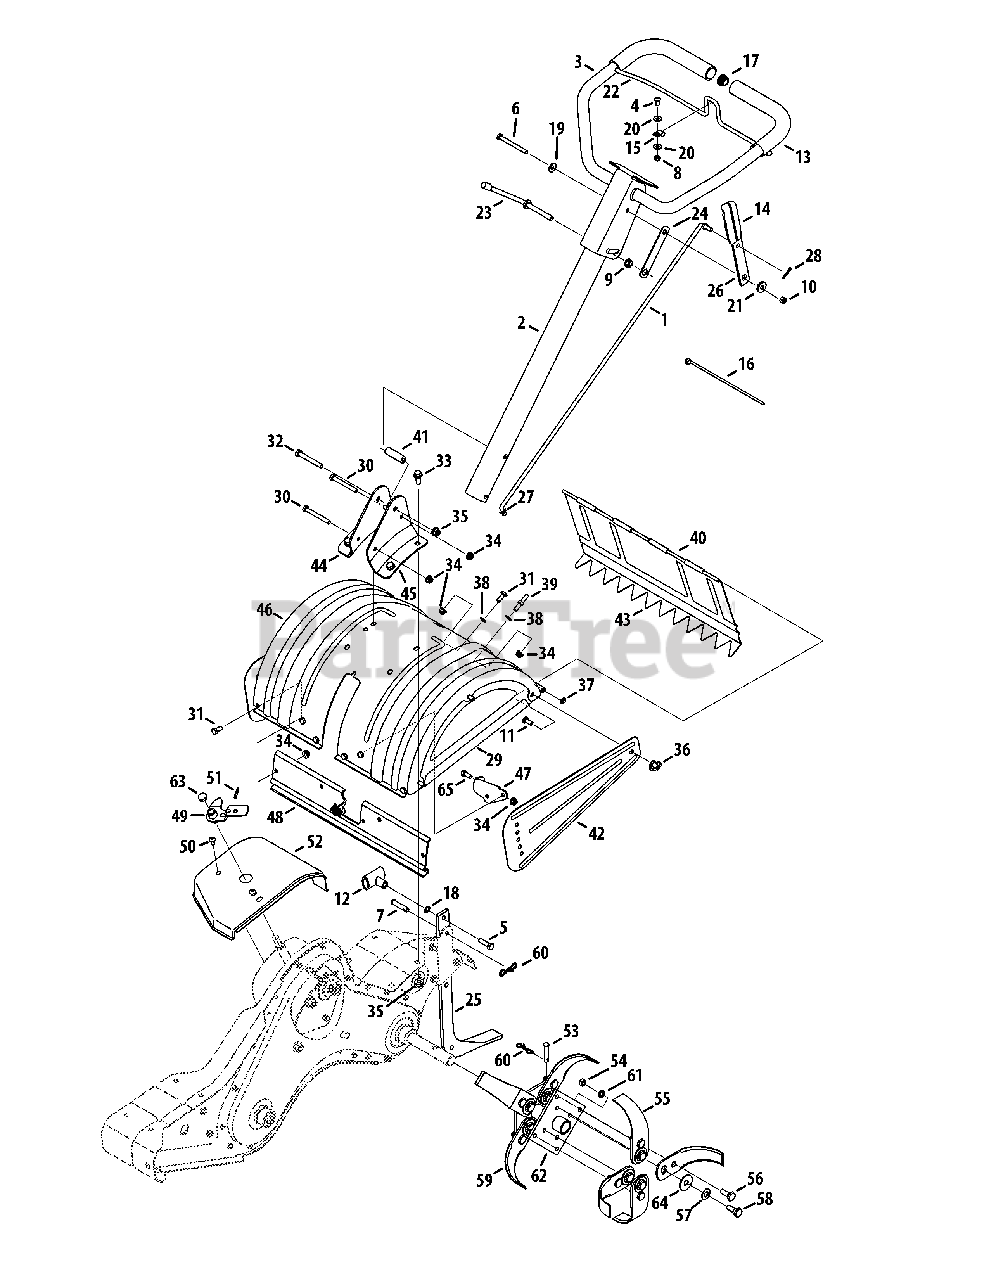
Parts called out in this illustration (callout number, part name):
1	Shaft Rod
2	Lower Handle Tube Assembly
3	Upper Handle Assembly
4	Screw, 1/4-20 x 0.625
5	Hex Head Screw, 3/8-16:1.25
6	Hex Head Screw, 5/16-18 x 3.25
7	Clevis Pin, .375 X 1.75
8	Hexlock Nut, 1/4-20
9	Flangelock Nut, 3/8-24
10	Hexlock Nut, 5/16-18
11	Stud, 5/16-18 x .75
12	Small Tee Knob
13	Foam Grip, .970 x 11.0
14	Grip, .1875 x 1.00
15	Battery Clamp, 5/16
16	Cable Tie, 8.5 LG
18	Washer, Flat, .385 x .620 x .033
19	Washer, Bell, .340 x .872 x .060
20	Washer, Flat, .260 x .720 x .060
21	Spacer, Shoulder, .50 x .190 x .360
23	Handle Adjustment Crank
24	Hex Nut Retainer Bracket
25	Tiller Depth Control
26	Shaft Rod Lever
27	Washer, Rubber, .33 ID x .125
28	Cotter Pin, .072 x 1.12 LG
29	End Cover Assembly
30	Hex Head Screw, 5/16-18 x 2.75
31	Hex Head Screw, 5/16-18 x .75
32	Hex Head Screw, 3/8-16 x 2.75
33	Hex Head Flange, 3/8-16 x .875
34	Flangelock Nut, 5/16-18
35	Flangelock Nut, 3/8-16
36	Wing Nut, 5/16-18 W/ Bell Washer
37	Speed Nut Cap, 1/4 ROD
38	Washer, Flat, .344 x .62 x .033
39	Screw, Hex, 5/16-18 x .75
40	Tiller Flap Rod
41	Spacer, .322 x .625 x 2.00
43	Rear Tine Shield
44	RH Handle Mount Bracket
45	LH Handle Mount Bracket
47	FRT Tine Shield Bracket
48	FRT Tine Shield Spacer Bracket
49	Shift Crank Assembly
50	Screw, 1/4-20 x .625
51	Spiral Pin, 3/16 x 1.0
53	Clevis Pin
54	Hex Nut, 3/8-24
55	13" Articulating Tine
56	Shoulder Bolt
57	Bell Washer, .515" ID x 1.14" OD
58	Shoulder Bolt
59	Tine Adapter Assembly, 18"
60	Internal Cotter Pin
61	Lock Washer
62	Tine Adapter Assembly
64	Washer, Flat, .51 x 1.5 x .07
65	Hex Head Screw, 5/16-18 x 1.00
